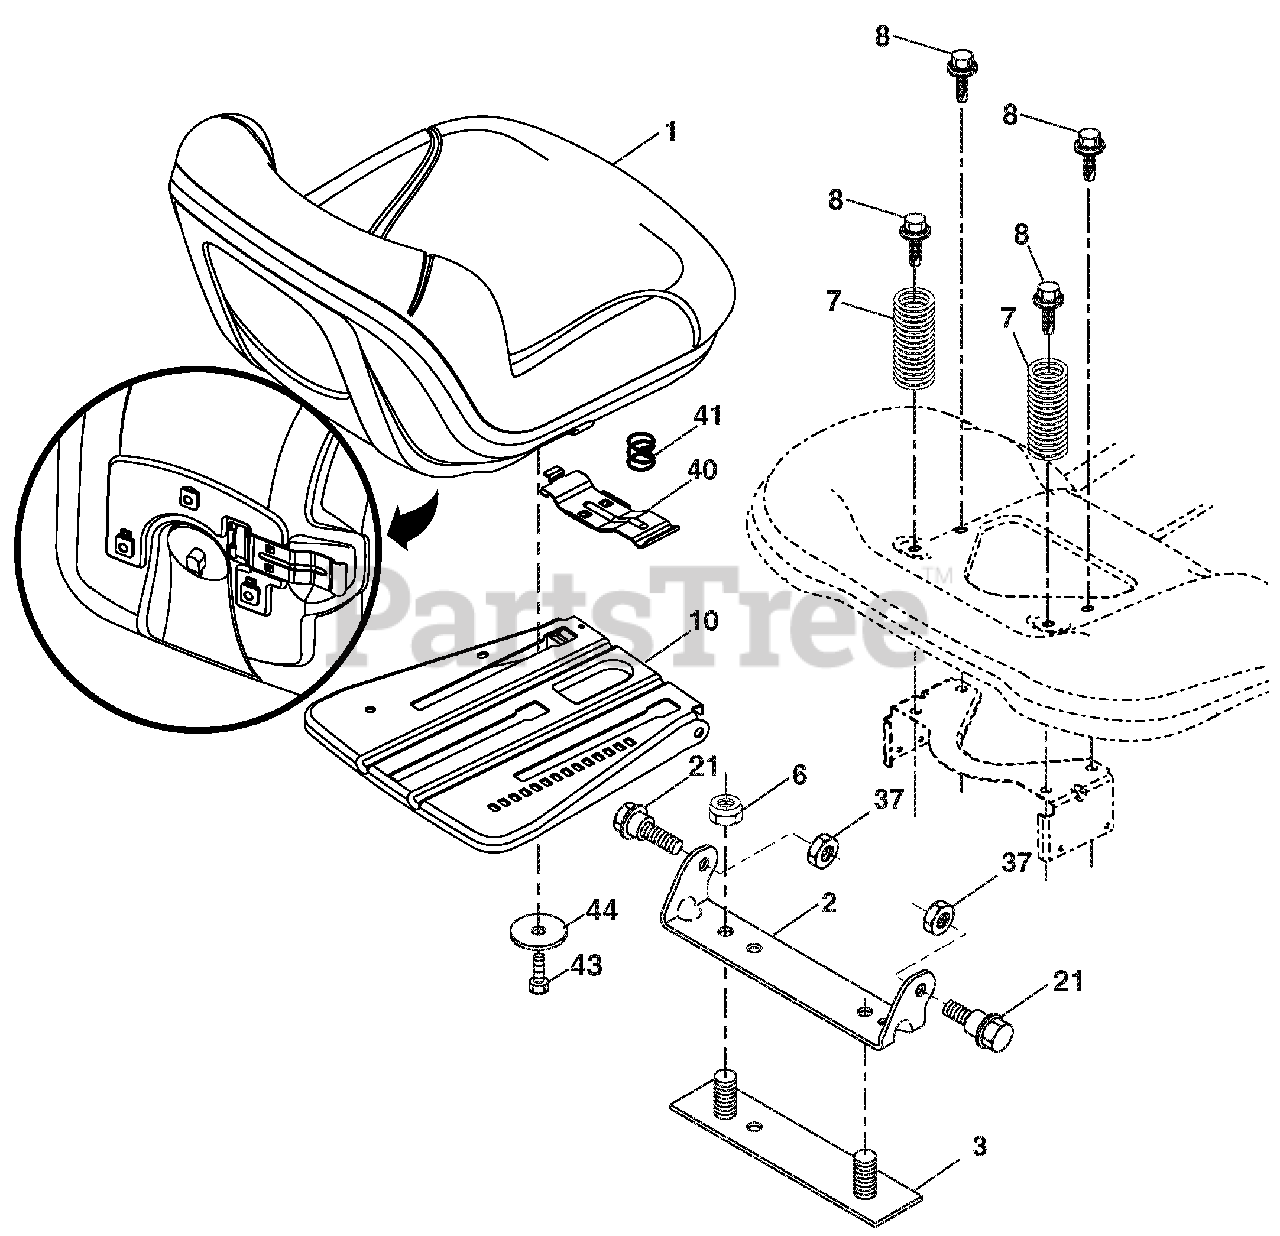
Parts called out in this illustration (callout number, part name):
1	SEAT.TA150.KB/SLD.BLK.ARIENS
2	BRACKET.PIVOT.FENDER.2002
3	STRAP ASM.FENDER.94
6	Locknut, Washer Insert 3/8-16
7	SPRING.SEAT.CPRSN.2.250.BLK.ZI
8	BOLT.5/16-18UNCX3/4 W/SEMS.BLK
10	PAN ASM.SEAT.3PT.
21	BOLT.SHLD.5/16-18 UNC-2A.BLK D
37	Locknut, Washer Insert 5/16-18
40	HANDLE.SLIDE.SEAT.TEX.MILSCO
41	SPRING.LATCH.SEAT.TEX
43	BOLT.FIN.HEX.3/8-16UNC X 3/4
44	WASHER.13/32 X 2 3/8 X 12GA.
